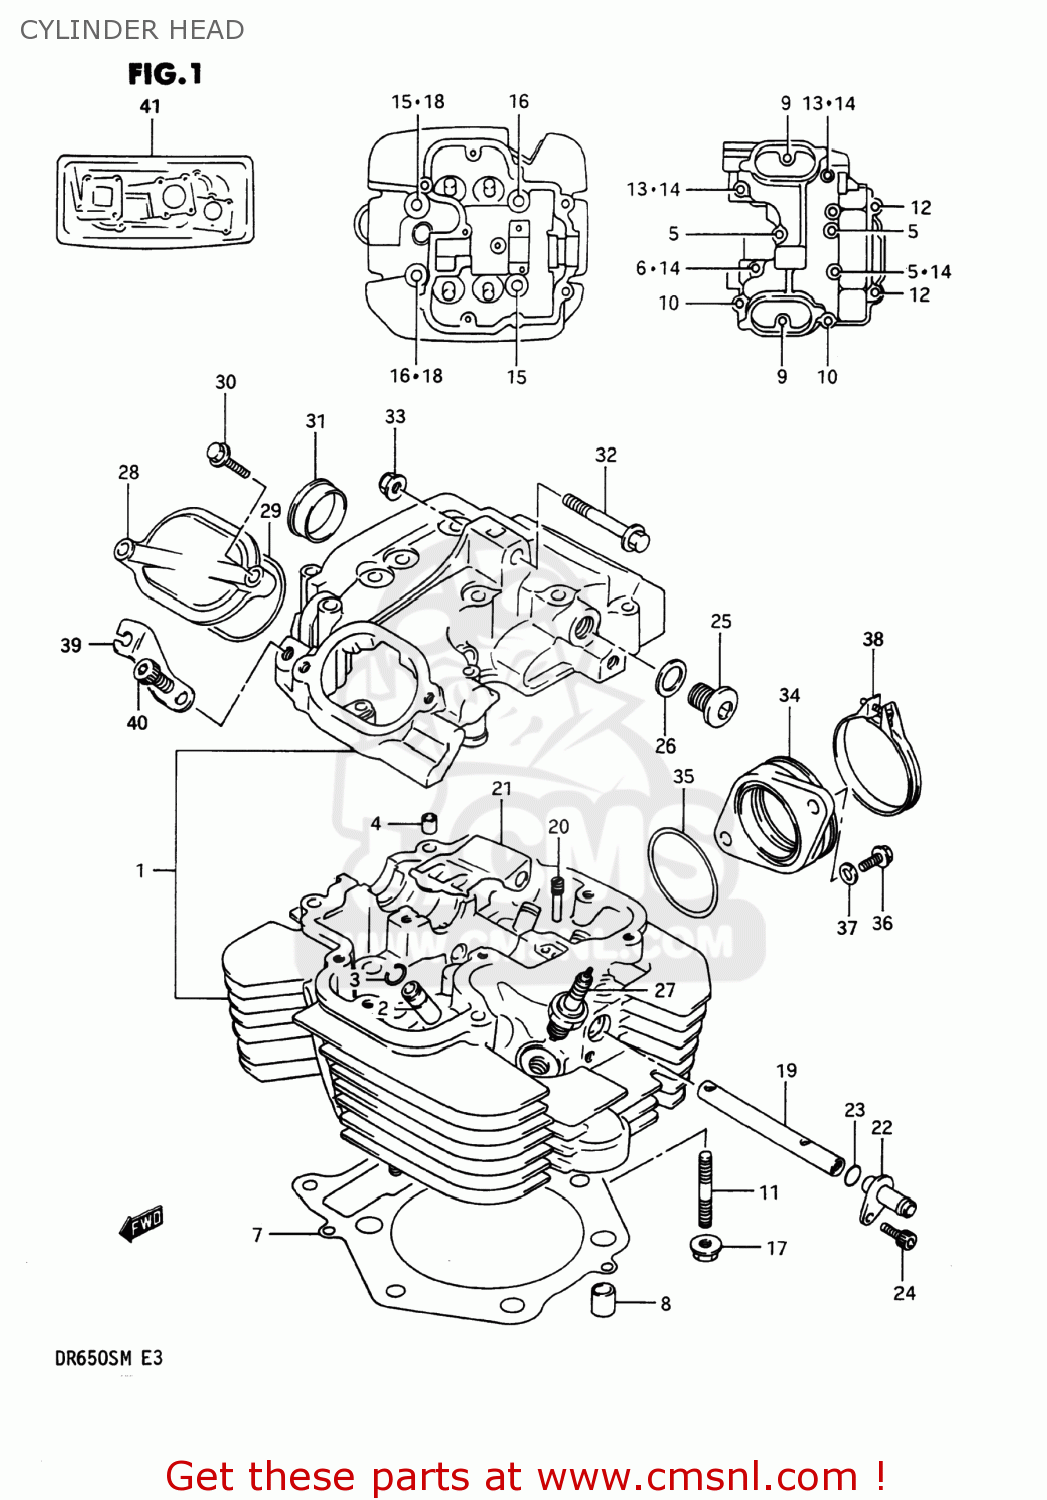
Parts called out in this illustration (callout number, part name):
1	HEAD ASSEMBLY,CYLINDER
2	GUIDE,VALVE
3	RING,SNAP
4	PIN(6.2X8X11)
5	BOLT ,6X60
6	BOLT 6X55
7	GASKET,CYLINDER HEAD (NAS)
8	PIN
9	BOLT 6X25
10	BOLT
11	STUD
12	BOLT(6X130)
13	BOLT ,6X60
14	GASKET (NAS)
15	BOLT(10X190)
16	BOLT(10X215)
17	NUT 8MM
18	GASKET(10.5X22X2) (NAS)
19	PIPE,CYLINDER HEAD OIL
20	SCREW (L:19.5)
21	PLATE,CYLINDER HEAD CHAMBER
22	UNION,CYLINDER HEAD OIL
23	O RING(D:1.3,ID:9.8)
24	BOLT
25	PLUG
26	GASKET(14X19.2X2) (NAS)
27	SPARK PLUG DP9EA-9
28	CAP,INSPECTION
29	O RING(D:2.4,ID:23)
30	BOLT
31	PLUG(OD:30)
32	BOLT
33	NUT
34	PIPE,INTAKE
35	O RING(D:2.4,ID:45.7)
36	PLUG ,6X20
37	WASHER
38	CLAMP
39	LEVER,DECOMP SHAFT RH
40	BOLT
41	GASKET SET
